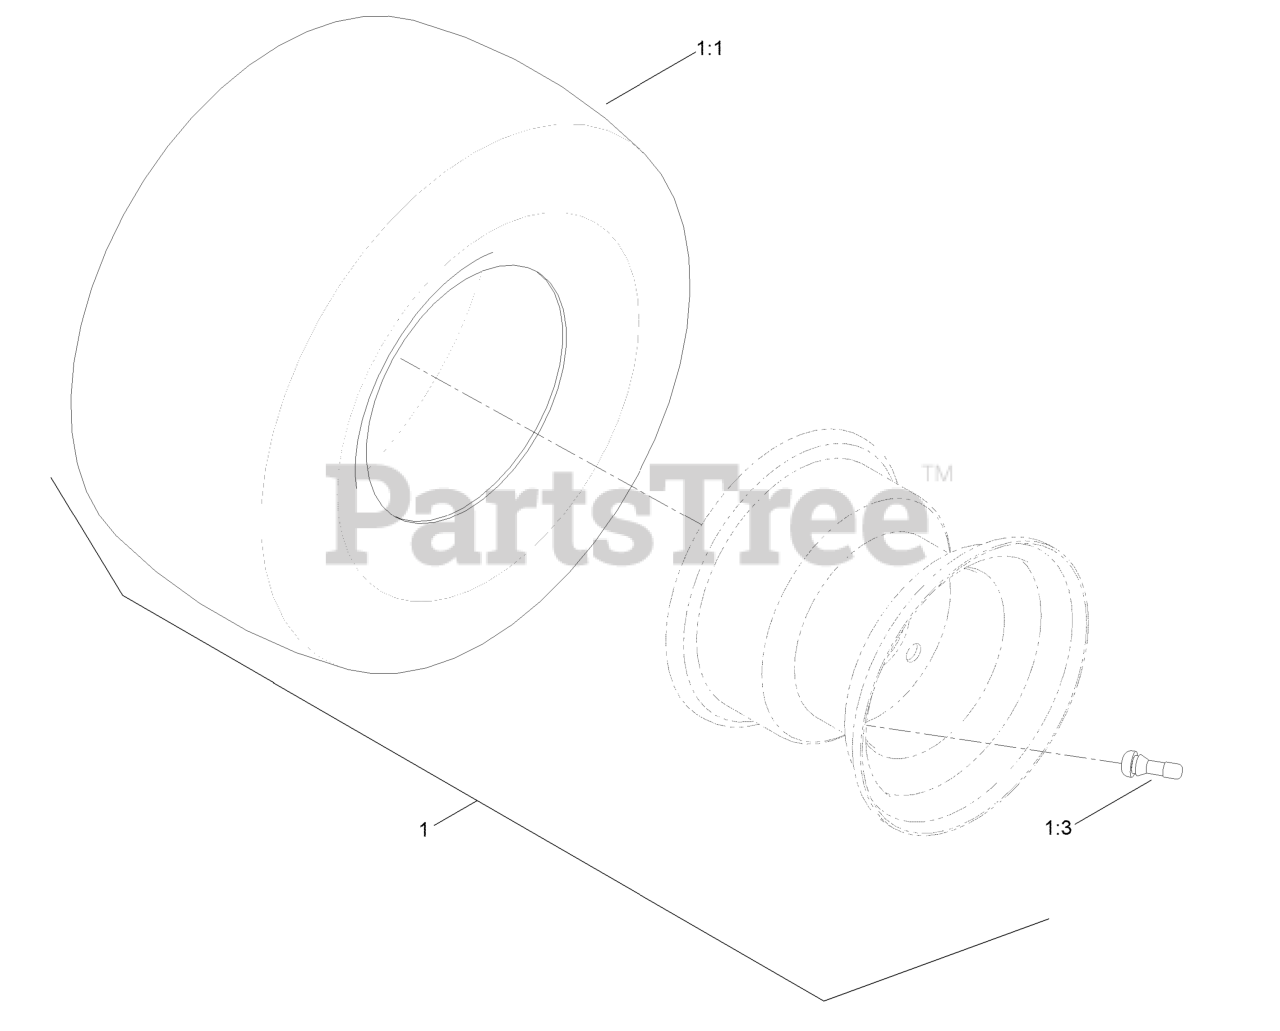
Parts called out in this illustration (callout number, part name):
1	2 PLY TIRE AND WHEEL ASM
1:1	TIRE-2PLY
1:3	Stem-Valve
